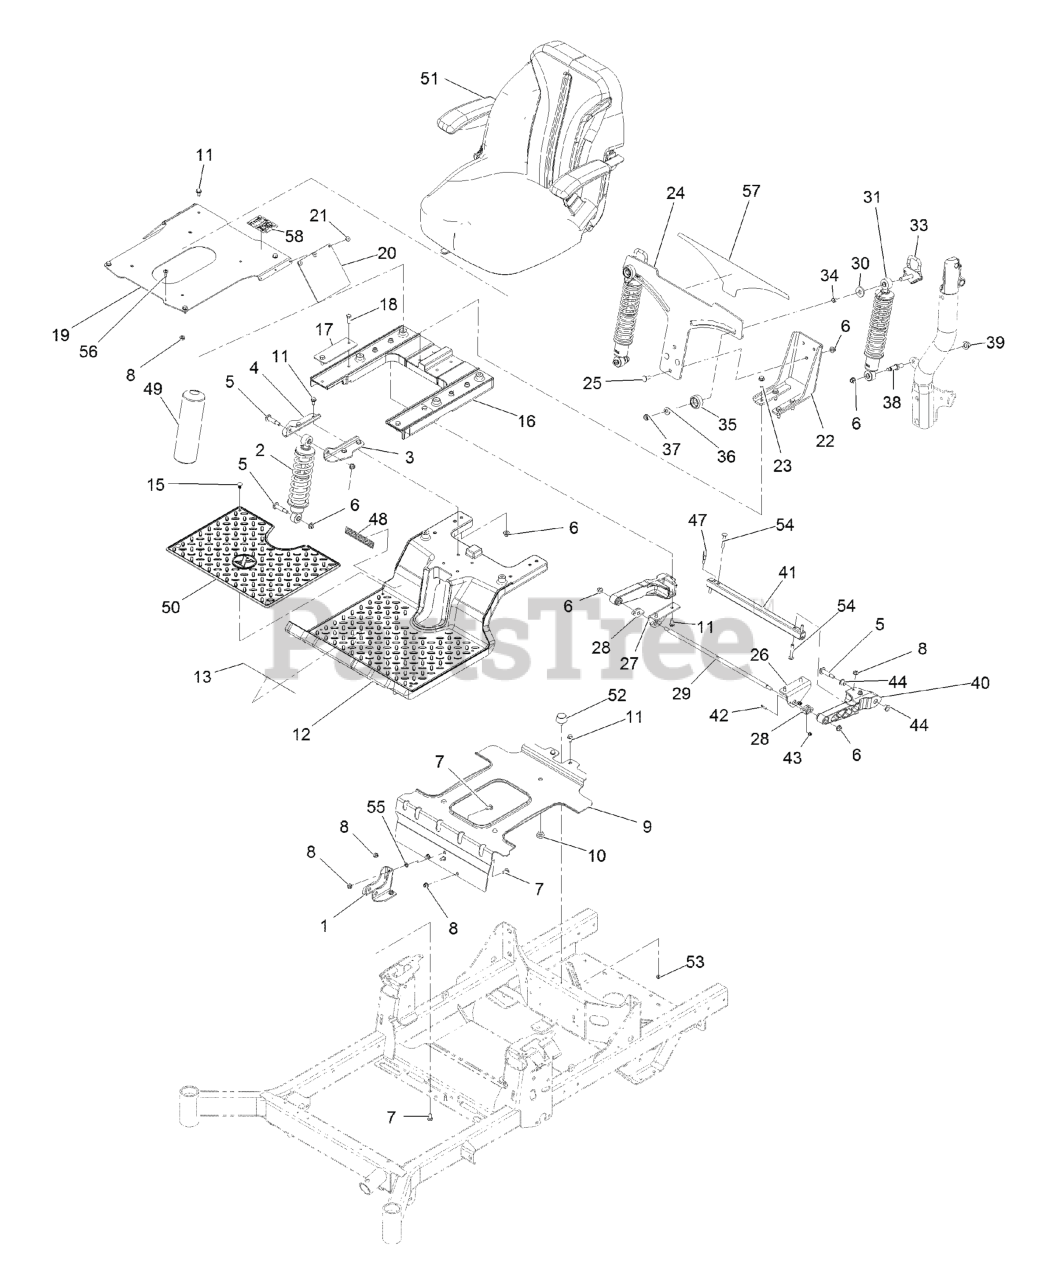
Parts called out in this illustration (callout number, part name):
1	BRACKET-SHOCK, FRONT LOWE
2	SHOCK/SPRING
3	BRACKET-SHOCK MOUNT, UPPE
4	BRACKET-SHOCK MOUNT, UPPE
5	BOLT-SHOULDER, HWH
6	NUT-HF, NI
7	SCREW-CARR
8	NUT-HF, NI
9	BRACKET-TANK
10	BUMPER-SEAT
11	Screw-HWH 5/16-18 X 3/4 Tf
12	SUBFRAME-FRONT
13	DECAL-DANGER
15	PLUG-PLASTIC
16	SUBFRAME-REAR
17	PLATE-BACKER
18	SCREW-HH
19	PLATE-SEAT
20	FLAP-RUBBER
21	RIVET-POP
22	BRACKET-MOUNT, LOWER
23	SCREW-THD
24	PLATE-MOUNTING, ADJ SHOCK
25	SCREW-CARR
26	BRACKET-ARM, TRAILING (LH
27	BRACKET-ARM, TRAILING (RH
28	BEARING-FLANGE
29	ROD-PIVOT
30	WASHER-PLASTIC
31	SHOCK/SPRING ASM
33	CAM LOCK ASM
34	BEARING-SLEEVE
35	KNOB-LOCK, CAM
36	WASHER-ADJUSTING
37	NUT-HEX
38	BOLT-SHOULDER
39	Nut-Lock 1/2-13
40	TRAILING ARM
41	TUBE-ARM, TRAILING
42	SCREW-CARR
44	BUSHING-FLANGE
47	CLAMP-HOSE
48	DECAL-RADIUS LOGO
49	COVER-SHOCK
50	FLOOR MAT
51	ASM-SEAT EXMARK
54	BOLT-CARR
55	NUT-PUSH
56	SCREW-SHOULDER
57	DECAL-ADJUSTMENT, RIDE
58	DECAL-AID, SERVICE
